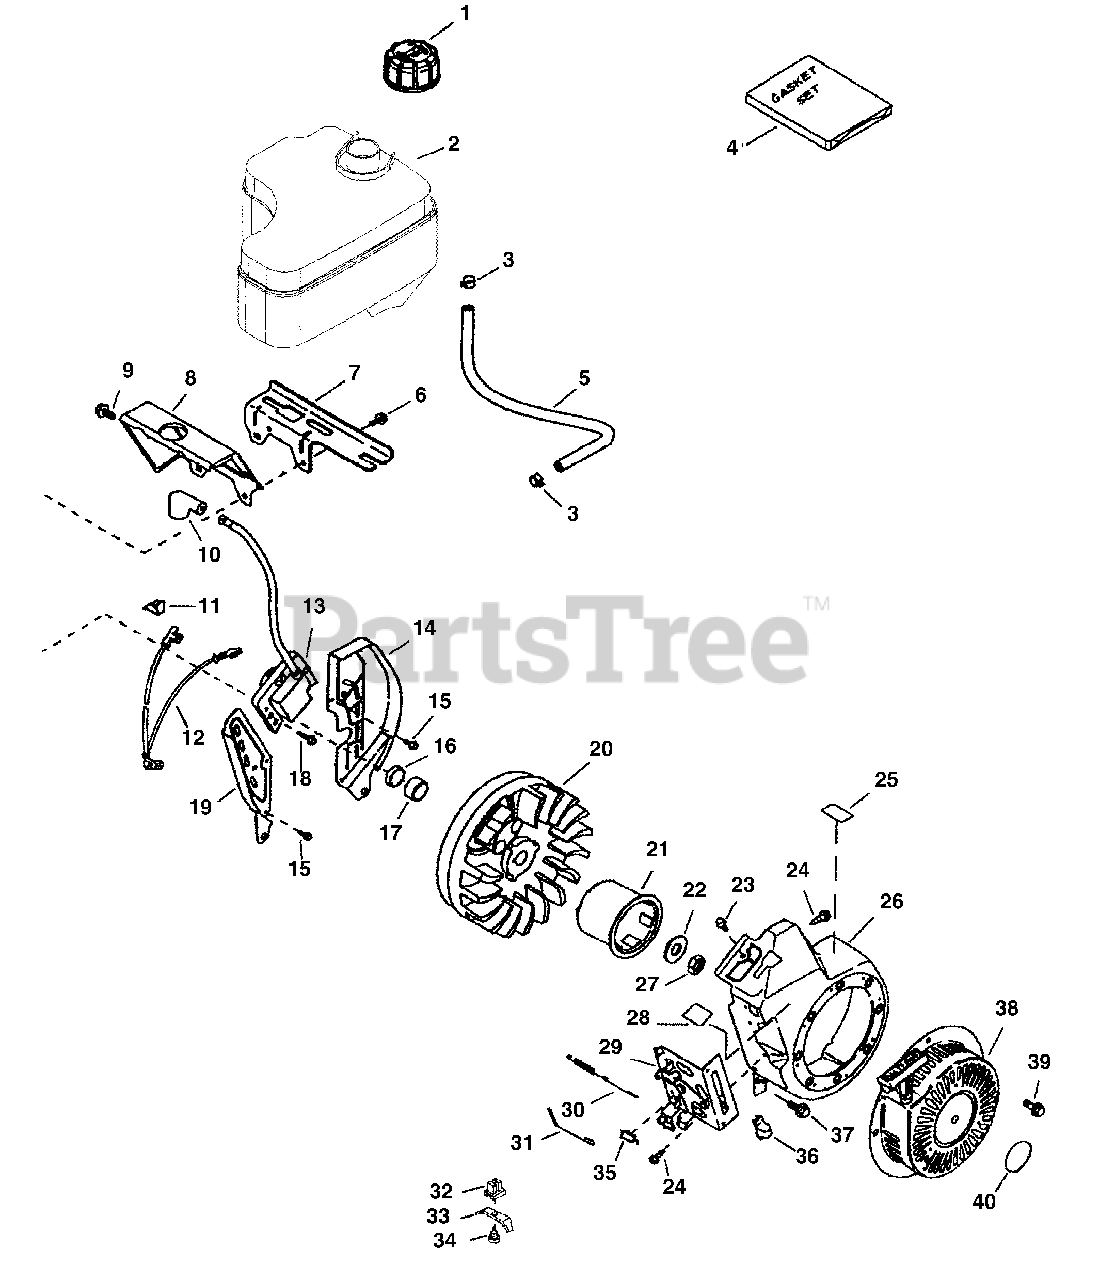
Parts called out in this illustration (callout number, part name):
1	Fuel Cap
2	Fuel Tank
3	Fuel Line Clamp
4	Gasket Set
5	Fuel Line
6	Screw, 1/4-20 x 7/8"
7	Fuel Tank Bracket
8	Blower Housing Extension
9	Screw, 10-24 x 9/16"
10	Spark Plug Cover
11	Wire Clip
12	Ground Wire
13	Solid State Ignition
14	Air Baffle (Right)
15	Screw, 10-24 x 9/16"
18	Screw, Torx T-15, 15/16"
19	Air Baffle (Left)
21	Starter Cup
22	Bell Washer
23	Screw, 1/4-20 x 31/64"
24	Screw, 10-32 x 1/2"
25	Lube Decal
26	Blower Housing
27	Flywheel Nut
28	Speed Control Decal
29	Control Bracket
30	Extension Spring
31	Governor Link
33	Ground Terminal
34	Screw, 8-32 x 3/8"
36	Control Knob
37	Screw, 1/4-20 x 31/64"
38	Rewind Starter
39	Screw, 1/4-20 x 31/64"
40	Starter Decal
